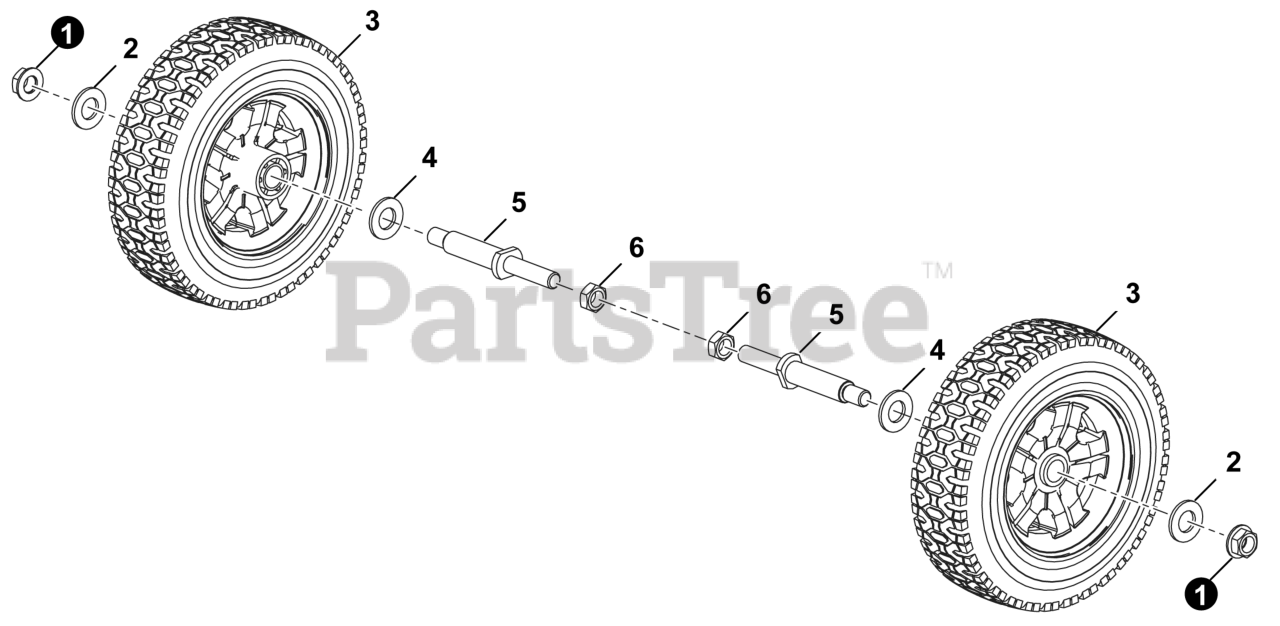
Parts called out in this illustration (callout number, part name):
2	WASHER, FLAT
3	WHEEL, FRONT
4	WASHER, FLAT
5	SHAFT, FRONT WHEEL
